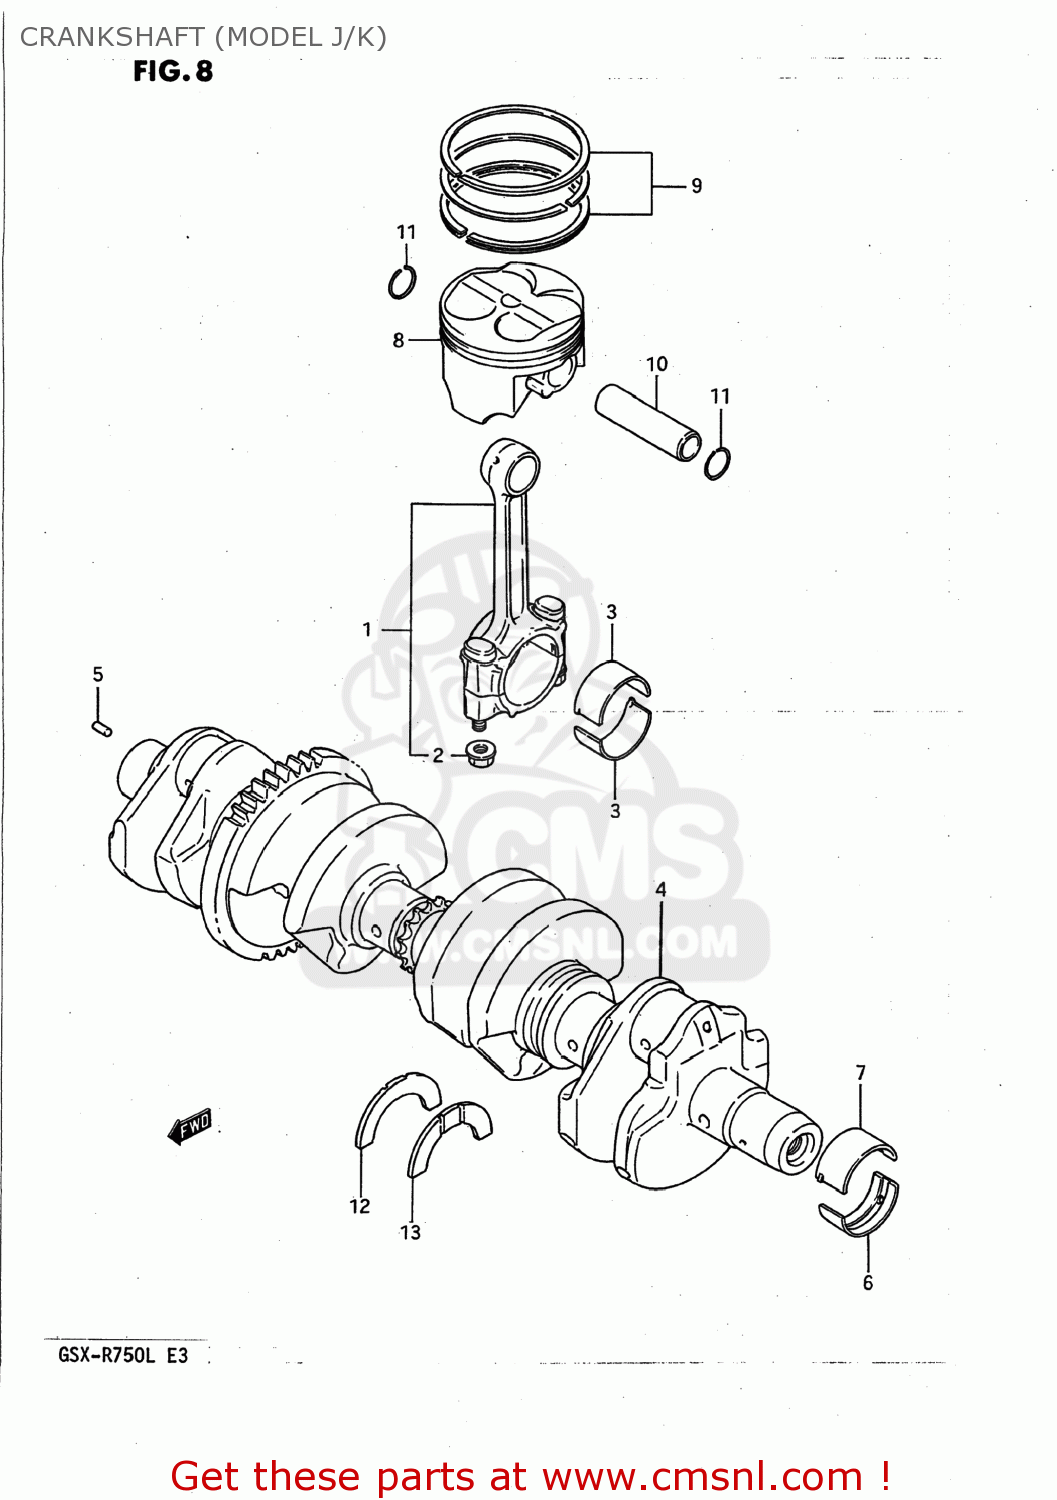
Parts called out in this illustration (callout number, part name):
1	CONNECTING ROD ASSY
2	NUT
3	BEARING,CRANK PIN
4	CRANKSHAFT
5	PIN
6	BEARING,CRANKSHAFT LWR
7	BEARING,CRANKSHAFT UPR
8	PISTON
9	RING SET,PISTON
10	PIN,PISTON
11	RING,SNAP
12	BEARING,CRANK THRUST(GREEN)
13	BEARING,CRANK THRUST(RED)
